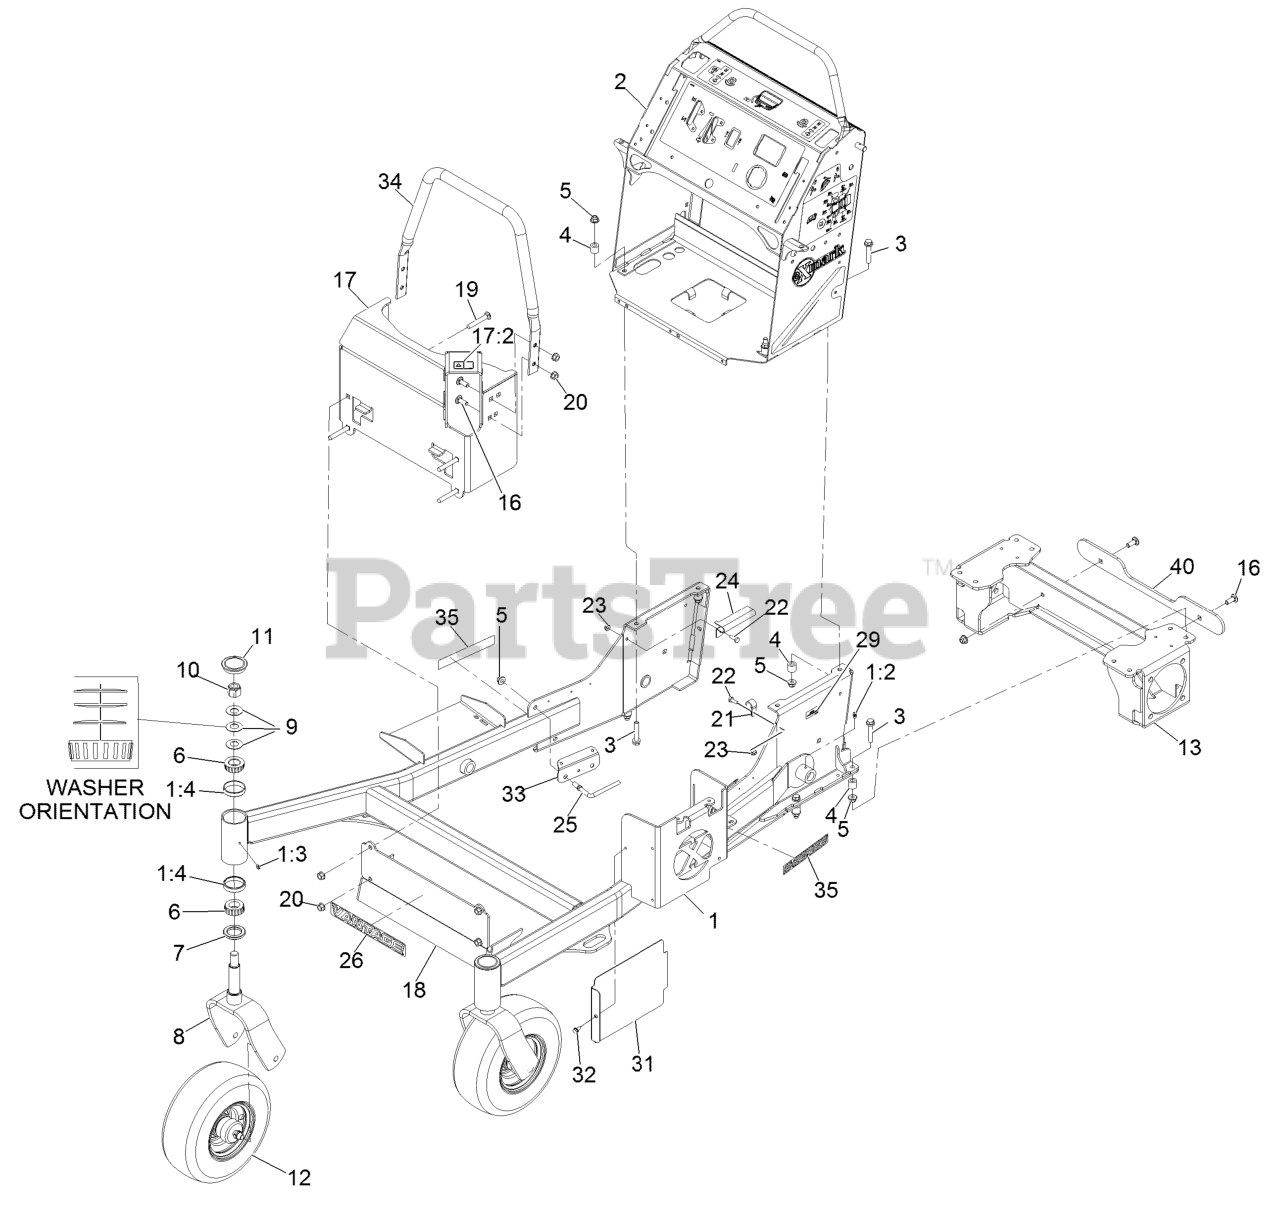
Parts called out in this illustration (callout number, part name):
1	FRONT FRAME ASM
1:2	FITTING-GREASE
1:4	CUP-BEARING
2	CONTROL TOWER ASM
3	SCREW-HHF
5	NUT-HF, NI
6	Cone-Bearing Tapered Roller
7	SEAL-GREASE
8	FORK-CASTER
9	WASHER-BELLVILLE
10	NUT-LOCK, NI
11	CAP-GREASE
12	WHEEL/TIRE AND BEARING AS
13	MOTOR FRAME WELDMENT
16	SCREW-CARR
17	ASM, MUFFLER GUARD W/ DEC
17:2	DECAL-WARNING
18	PANEL-GUARD
19	SCREW-CARR
21	CLAMP-CABLE
22	SCREW-HH
24	BRACKET-HOSE, FUEL (DOUBL
25	GUIDE-HOSE, SUPPORT
26	DECAL-VANTAGE LOGO
29	Decal-Patent Ttco.Com
31	SHIELD-HEAT, TALL
32	SCREW-HWH
33	GUARD-HOSE
34	TUBE-GUARD
35	DECAL-S-SERIES
40	PLATE, BUMPER SPACER
